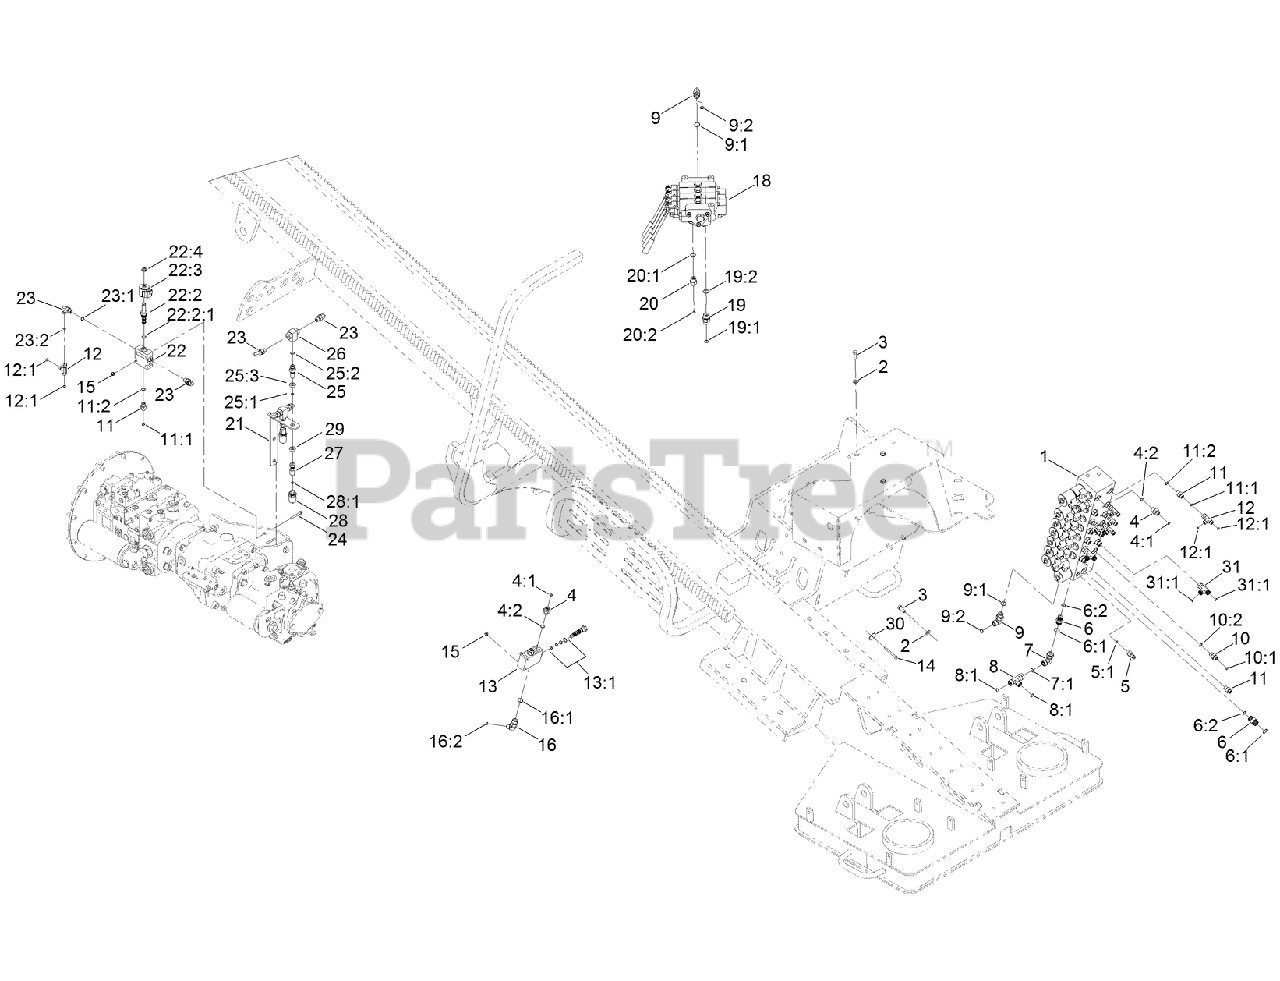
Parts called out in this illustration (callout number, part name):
1	9 SECTION HYD VALVE ASM
2	WASHER-FLAT
3	SCREW-HH
4	FITTING-STR,ORIF
4:1	O-RING
4:2	O-RING
5	FITTING-QUICK
5:1	O-RING
6	FITTING-STRAIGHT
6:1	O-RING
6:2	O-RING
7	FITTING-HYD
7:1	O-RING
8	FITTING-HYD, TEE
8:1	O-RING
9	FITTING-ELBOW-90 DEG
9:1	O-RING
9:2	O-RING
10	FITTING-STRAIGHT
10:1	O-RING
10:2	O-RING
11	FITTING-STRAIGHT
11:1	O-RING
11:2	O-RING
12	FITTING-HYD
12:1	O-Ring
13	HYD FLOW DIVIDER VALVE ASM
13:1	SEAL KIT
14	SCREW-FLANGE, METRIC
15	NUT-FLANGE, NI
16	FITTING-ELBOW 90
16:1	O-RING
16:2	O-RING
18	4 SPOOL HYD VALVE ASM
19	FITTING-STRAIGHT
19:1	O-RING
19:2	O-RING
20	FITTING-STR
20:1	O-RING
20:2	O-RING
21	BRACKET-VALVE, SHUTTLE
22	VALVE-SOLENOID
22:2	Valve-3 Way
22:2:1	SEAL KIT
22:3	E COIL-12V DC
22:4	NUT-COIL
23	FITTING-ELBOW 90
23:1	O-RING
23:2	O-RING
24	SCREW-HHF
25	FITTING-STRAIGHT
25:1	O-RING
25:2	O-RING
25:3	NUT-LOCK
26	VALVE-SHUTTLE, LOAD
27	FITTING-STRAIGHT
28	TRANSDUCER
28:1	O-RING
29	NUT-LOCK
30	WASHER-FLAT
31	FITTING-TEE, SWIVEL NUT
31:1	O-RING
